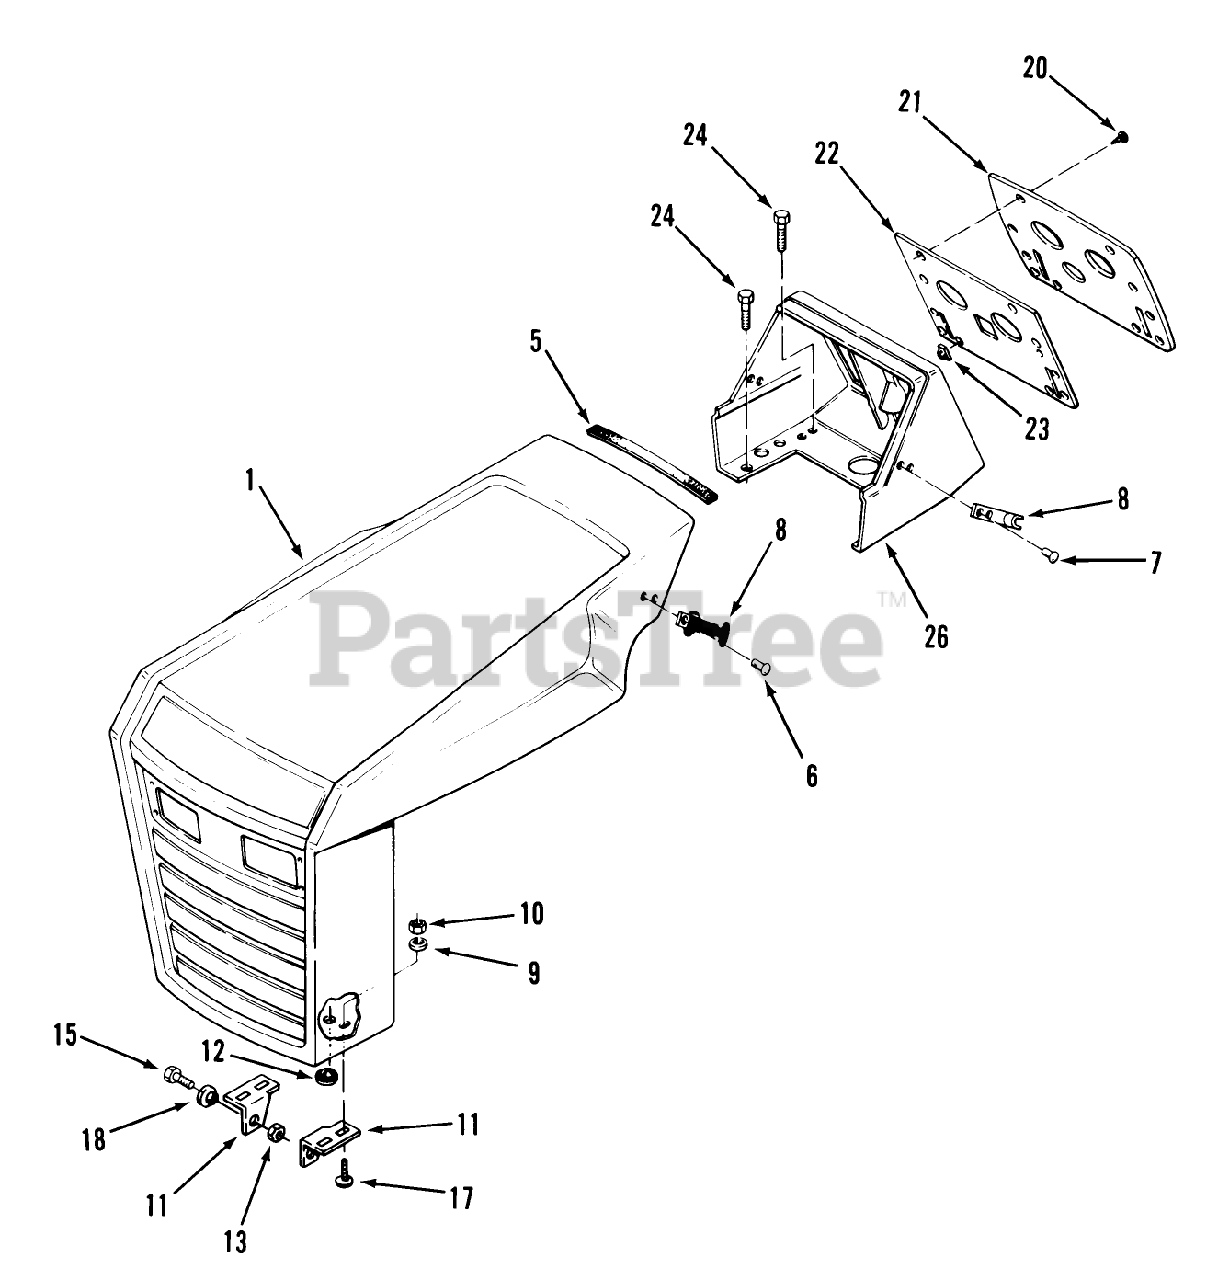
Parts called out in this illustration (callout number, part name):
4	SCREW
10	SCREW
12	SCREW
17	SCREW
18	GROMMET
